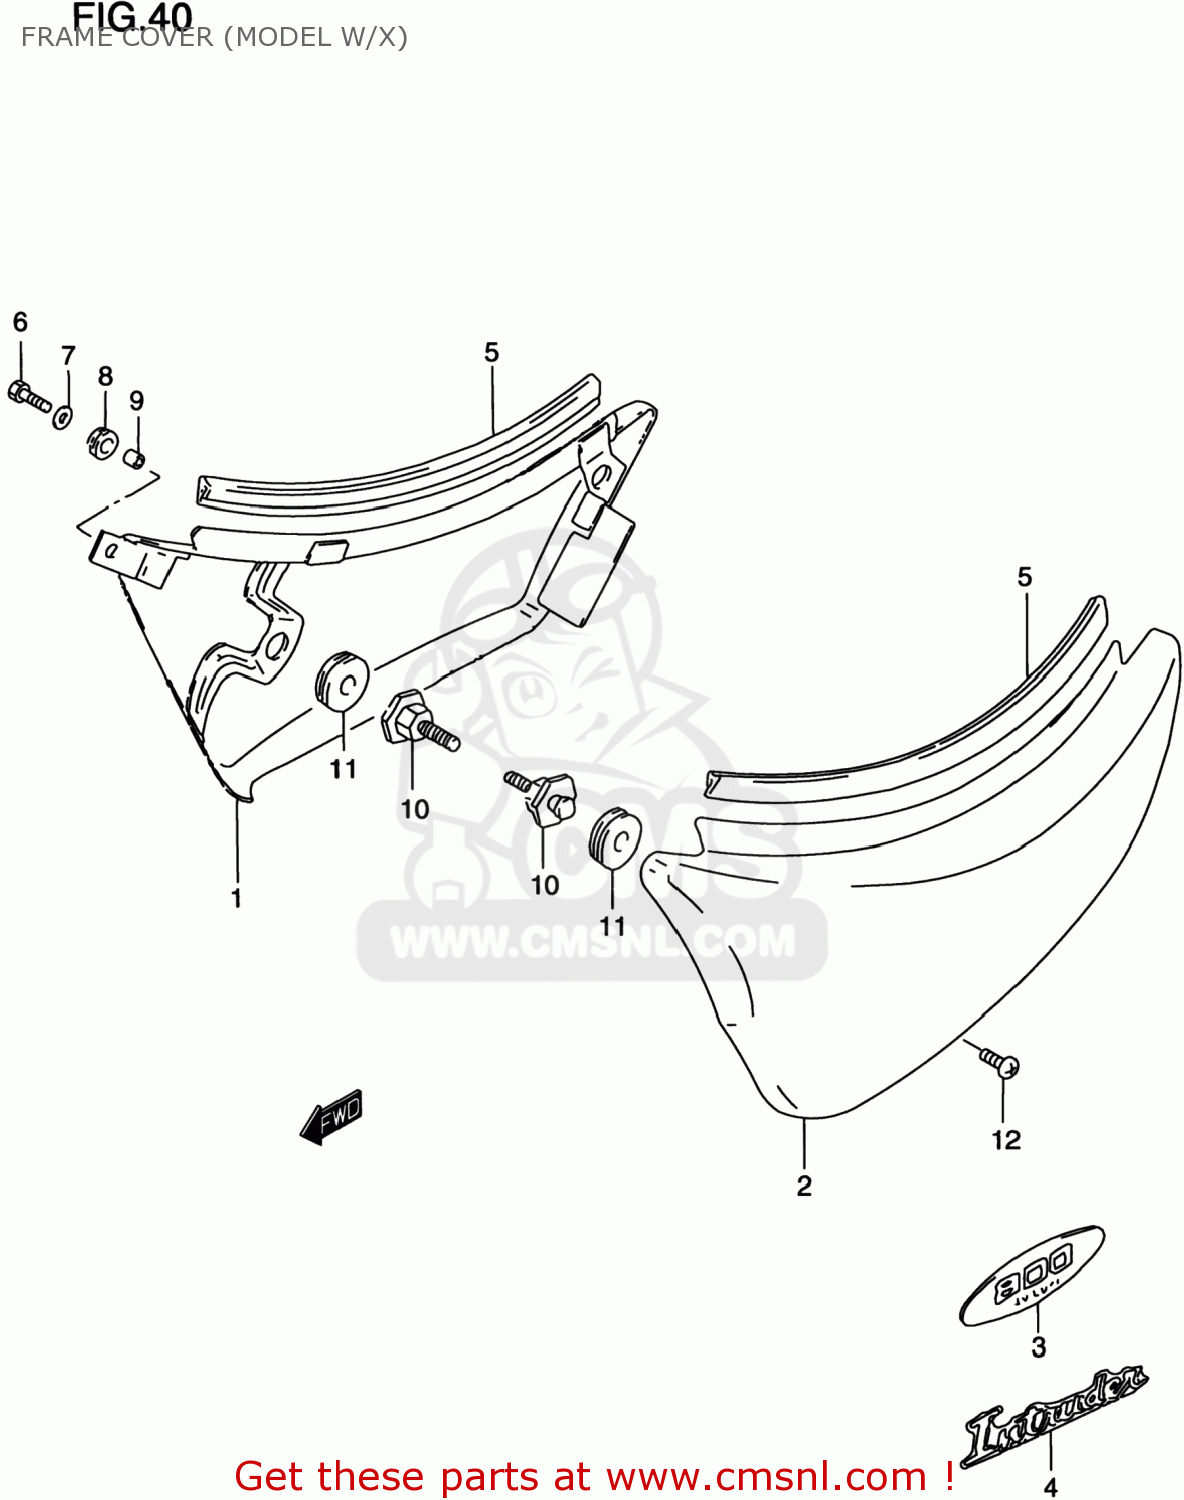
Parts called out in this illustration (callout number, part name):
1	COVER COMP,FRAME,RIGHT
2	COVER,FRAME,L(RED)
3	EMBLEM,FRAME COVER
4	EMBLEM,FRAME COVER
5	MOLDING
6	BOLT
7	WASHER(6.5X18X1.6)
8	CUSHION
9	SPACER(6.1X8X5.2)
10	BOSS,FRAME COVER
11	CUSHION
12	SCREW 6X10
